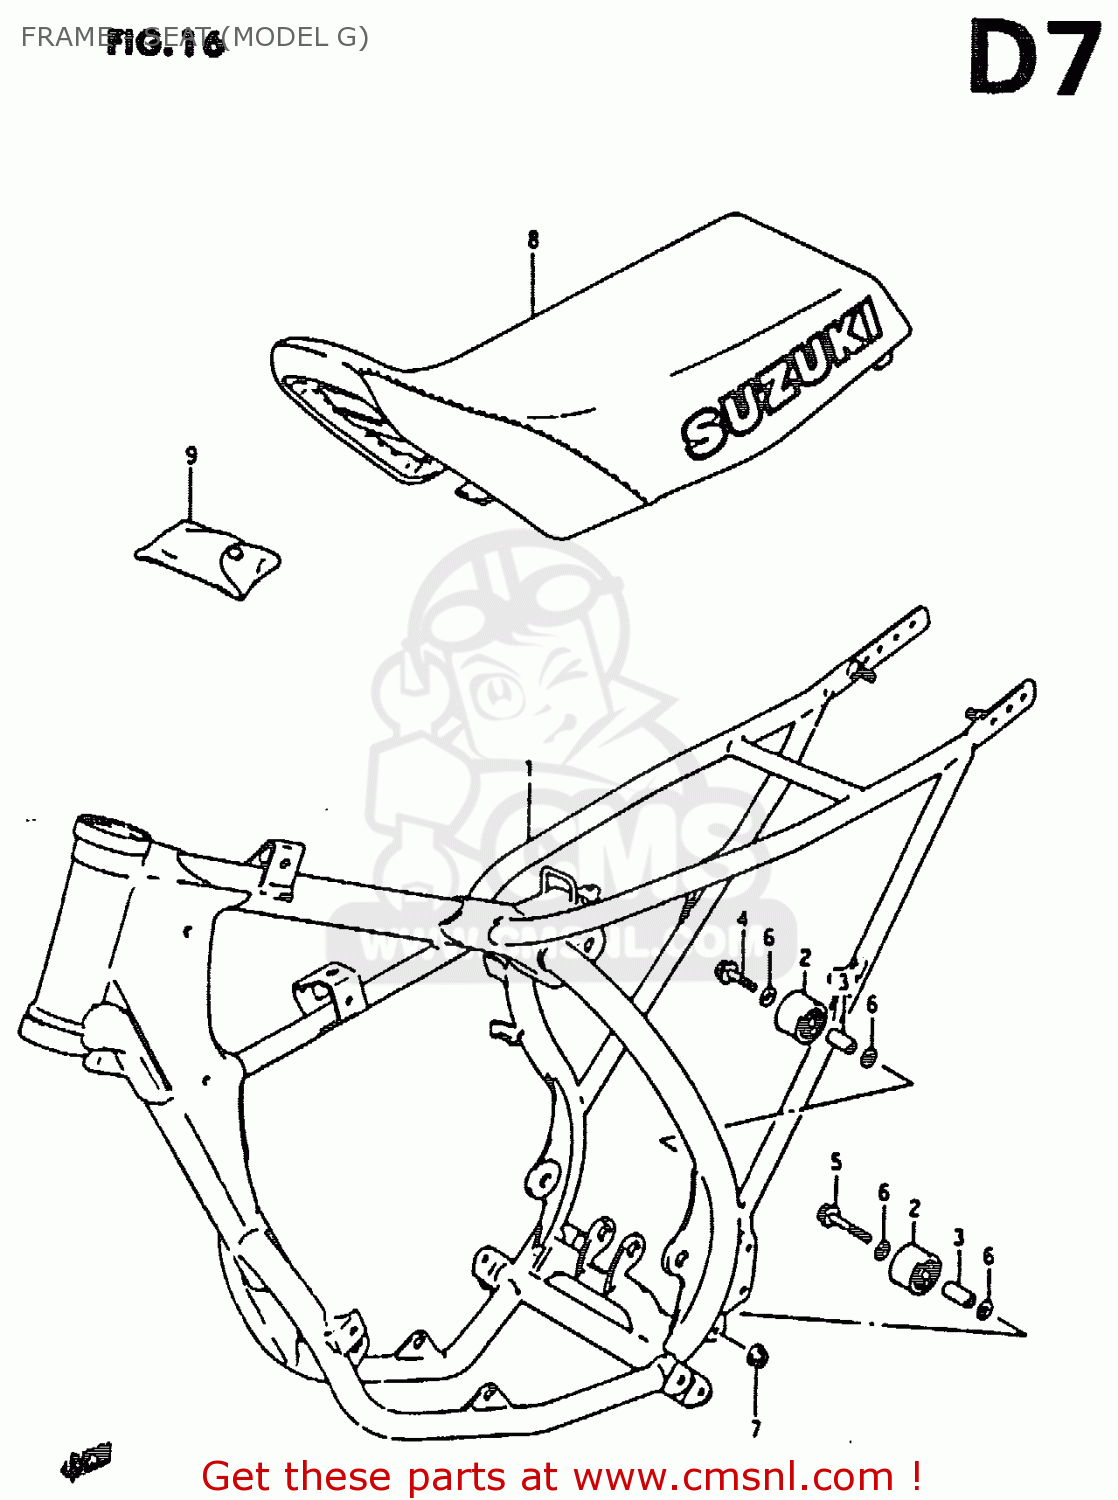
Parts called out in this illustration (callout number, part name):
1	FRAME
2	ROLLER, CHAIN CONTROL
3	SPACER(8.6X12X25.5)
4	BOLT(8X41)
5	BOLT(8X45)
6	WASHER
7	NUT
8	SEAT ASSEMBLY
9	TOOL SET
